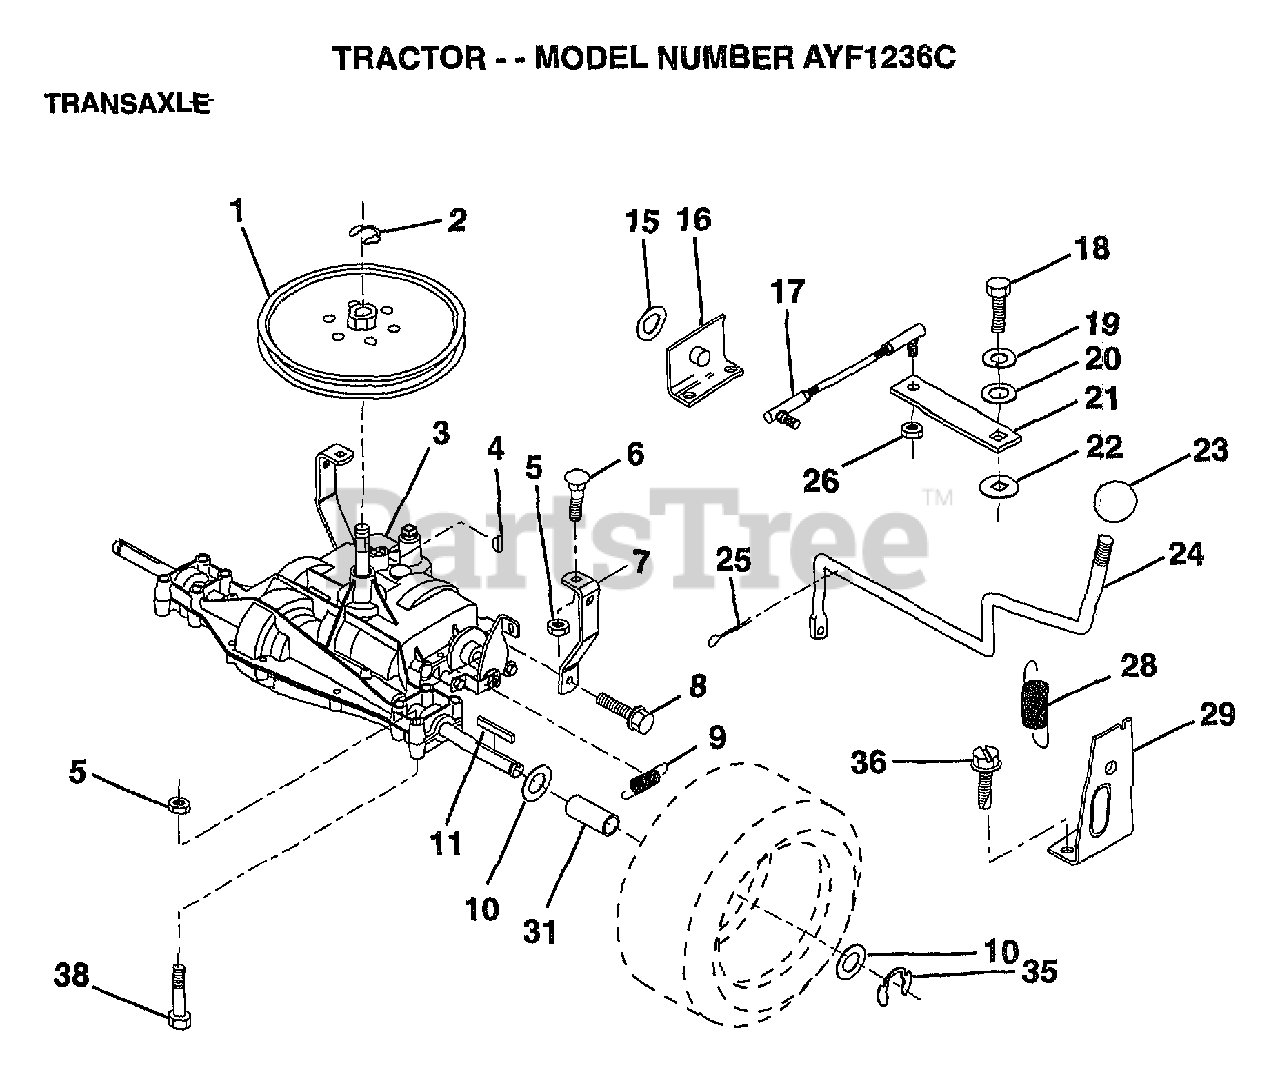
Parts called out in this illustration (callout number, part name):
1	PULLEY
6	BOLT
7	"STRAP,TORQUE"
8	SCREW
9	SPRING.BRAKE.RETU
10	WASHER
11	SQUARE KEY
16	SUPPORT HANDLE SHIFT LH
17	LINK SHIFT
18	BOLT.1/4-28.W/PAT
19	LOCKWASHER
20	WASHER LT
22	WASH-SHFT PLT LT
23	KNOB T (1/2-HOLE)
24	"ROD,SHIFT"
25	PIN COTTER 1/8
26	NUT.LOCK.5/16-24
28	"SPRING,EXT"
29	"SUPT,HDLE RH"
31	SPACER AXLE
35	E-RING LT
36	SCREW, HEX WASHER HD. CUTTING 1/4-20X1/2
38	BOLT.HEX.FLGHD
